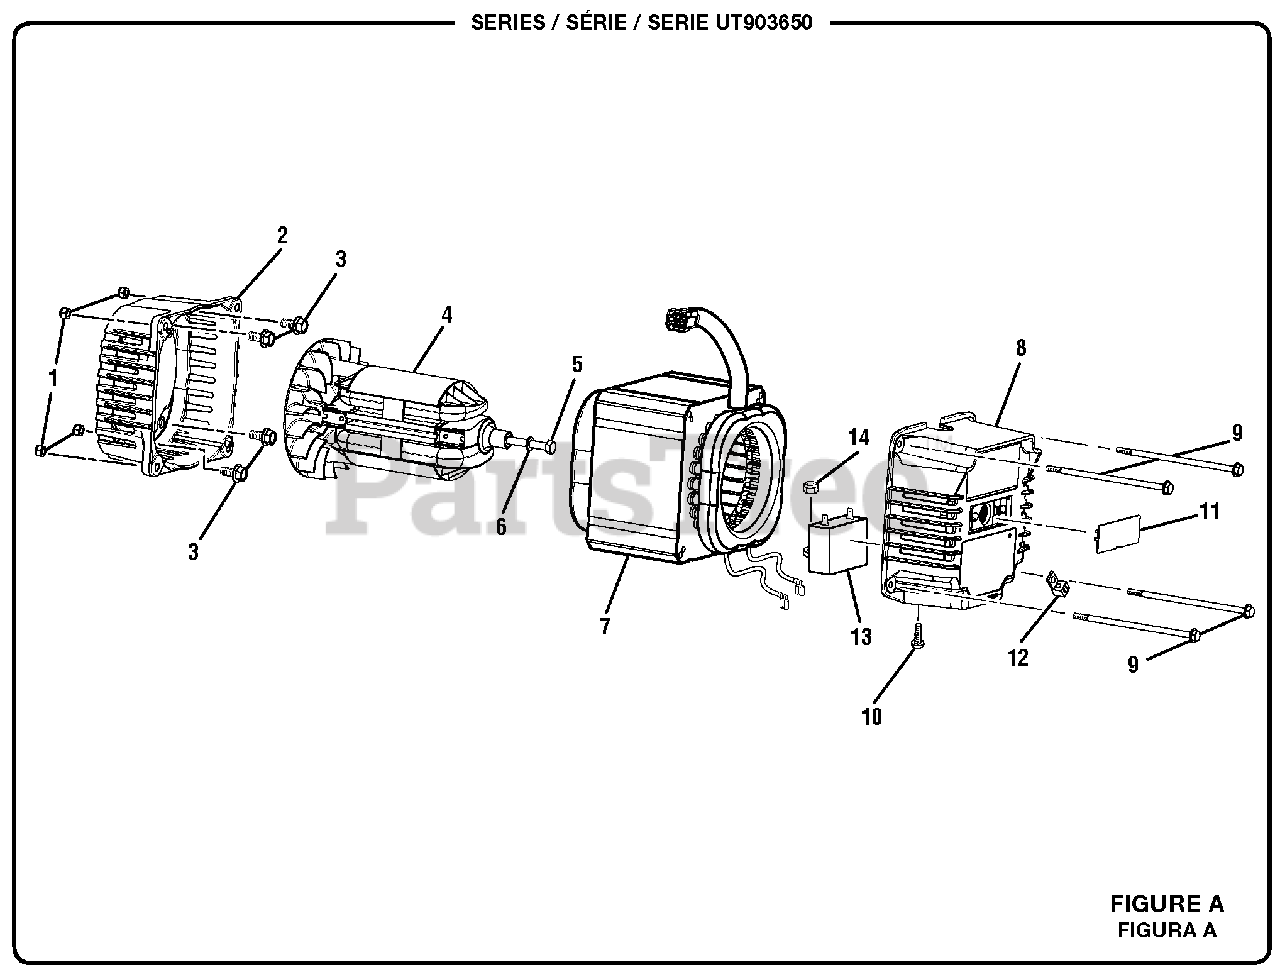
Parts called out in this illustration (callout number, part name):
1	Lock Nut (1/4-20)
2	Engine Adapter
3	Bolt (5/16-24 x 5/8
5	Bolt (5/16-24 x 7-3/4 in, Hex Hd)
6	Lock Washer (5/16
9	Bolt (1/4-20 x 5-1/2 in Hex Hd)
10	Bolt (M5 x 16 mm, Pan Hd)
11	Brush Cover
12	Ground Lug
13	Capacitor
14	Hex Nut (M5)
